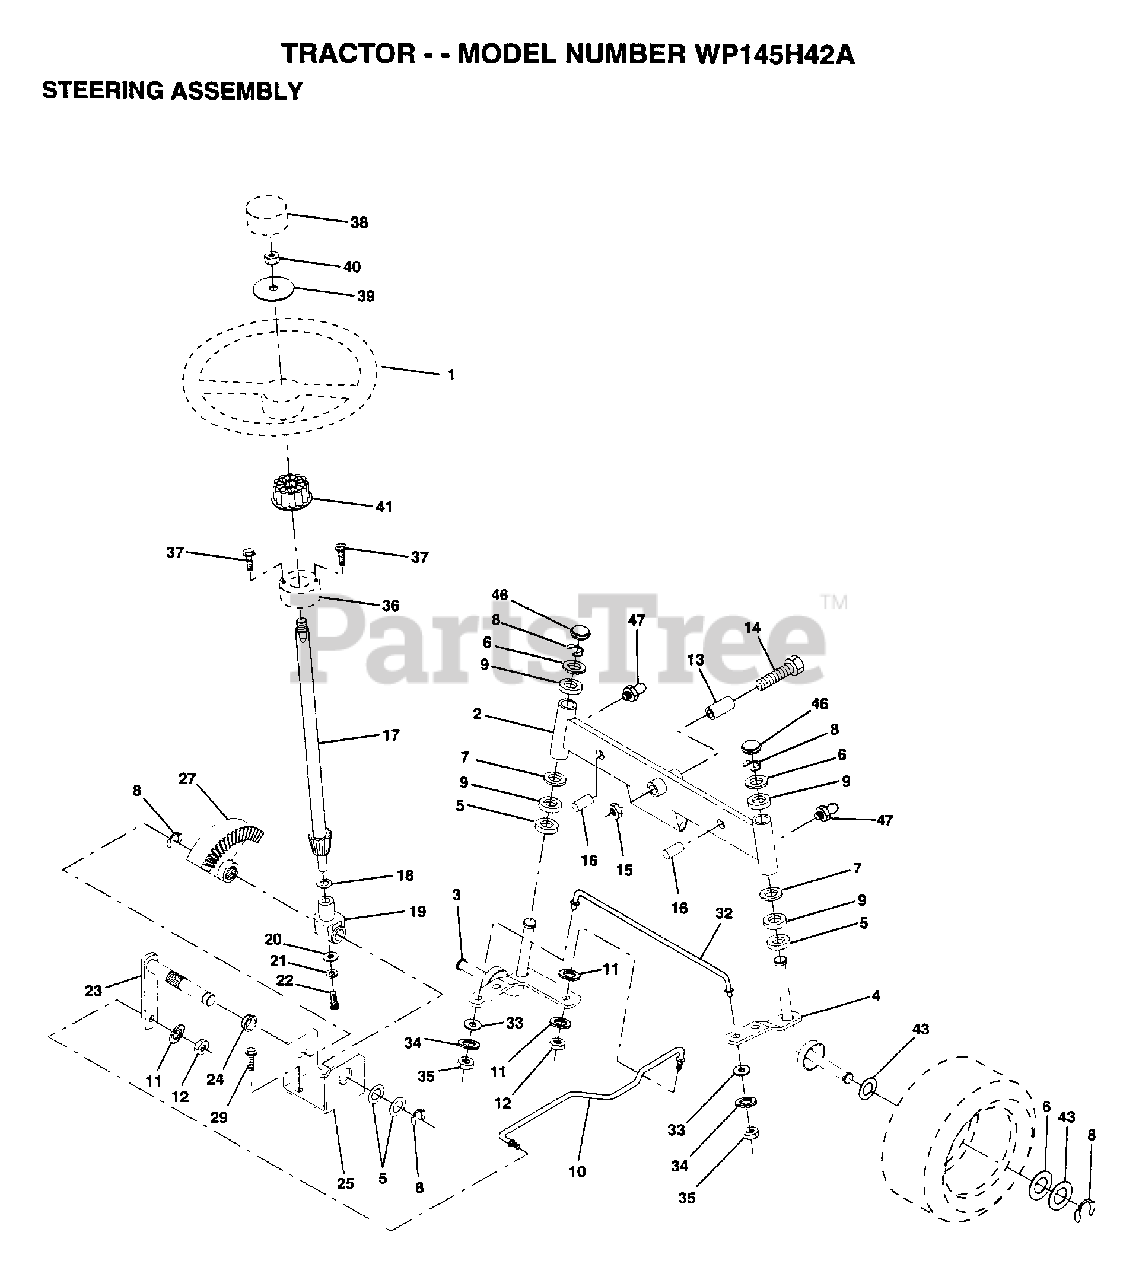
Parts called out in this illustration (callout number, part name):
2	AXLE ASM FRONT
3	SPINDLE LH
4	SPINDLE RH
5	WASHER .T
6	WASHER
7	WASHER
8	RING
9	COL. SRTG. BEAR.
11	LOCKWASHER
13	BEARING
14	BOLT HEX 5/8-11
15	"NUT-LOC,FLANGE LT"
16	AXLE PIN
17	STEERING SHAFT
18	THRUST WASHER
19	SUPPORT.SHAFT
21	LOCKWASHER
22	"SCREW,SPECIAL"
24	NYLINER T
25	"BRKT,STEERING"
26	BUSHING.DRAGLINK
27	GEAR SECTOR
28	WASHER
29	SCREW
30	COTTER PIN
32	TIE ROD
33	WASHER M
34	LOCKWASHER
36	BUSHING.STRG.3/4
37	SCREW.10-24X1/2
38	"INSERT,STR WHEEL"
39	WASHER
41	ADAPTER LT
43	WASHER
46	CAP
47	ZERK M
